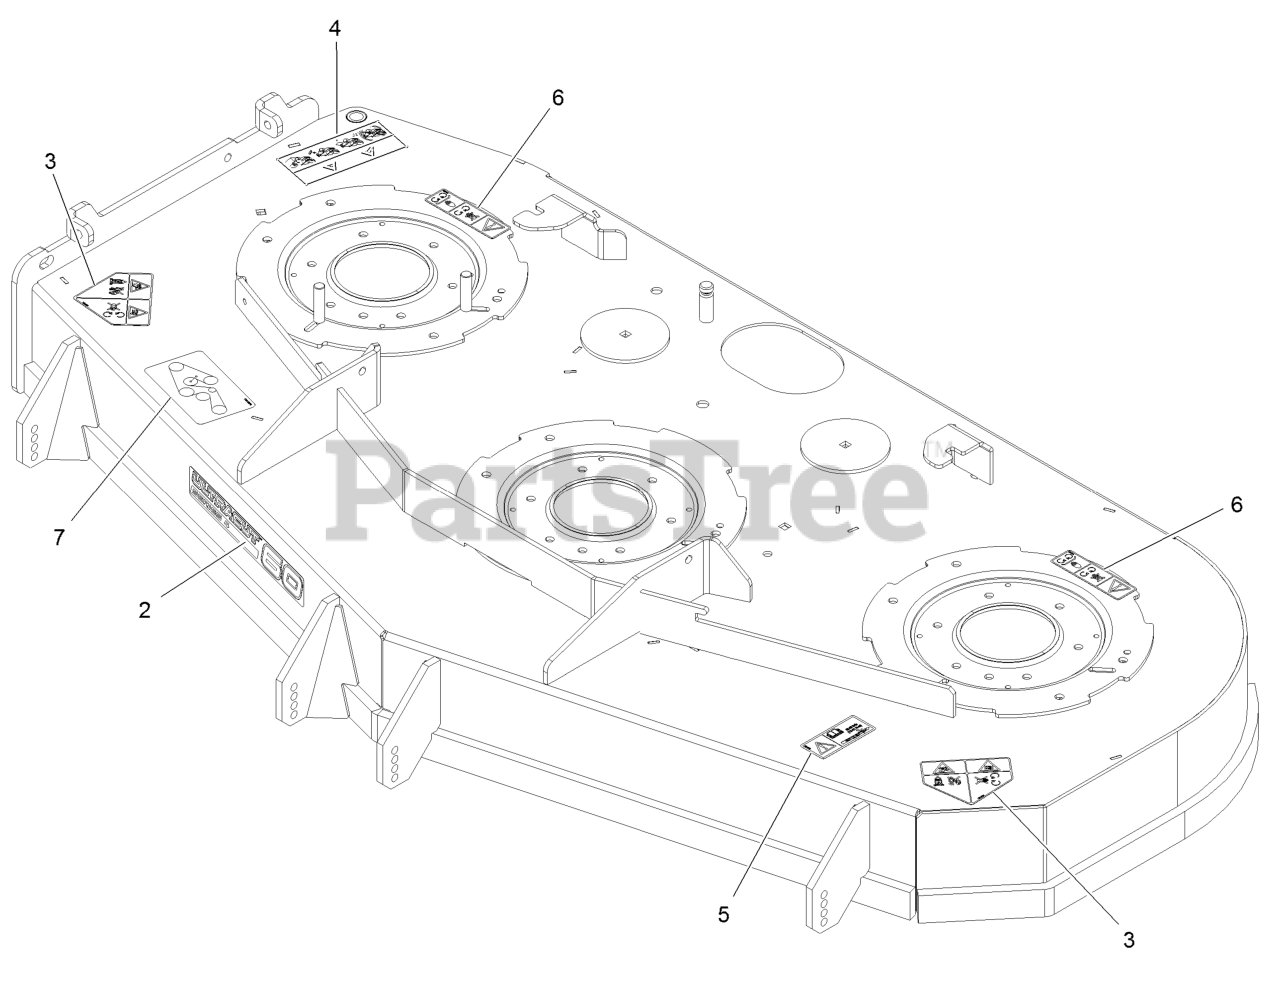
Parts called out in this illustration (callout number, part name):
2	DECAL, 604
3	DECAL-DANGER
4	DECAL-WARNING, BAGGER
5	DECAL-BOLT TORQUE
6	DECAL-COVER, MISSING
7	DECAL-BELT ROUTING
